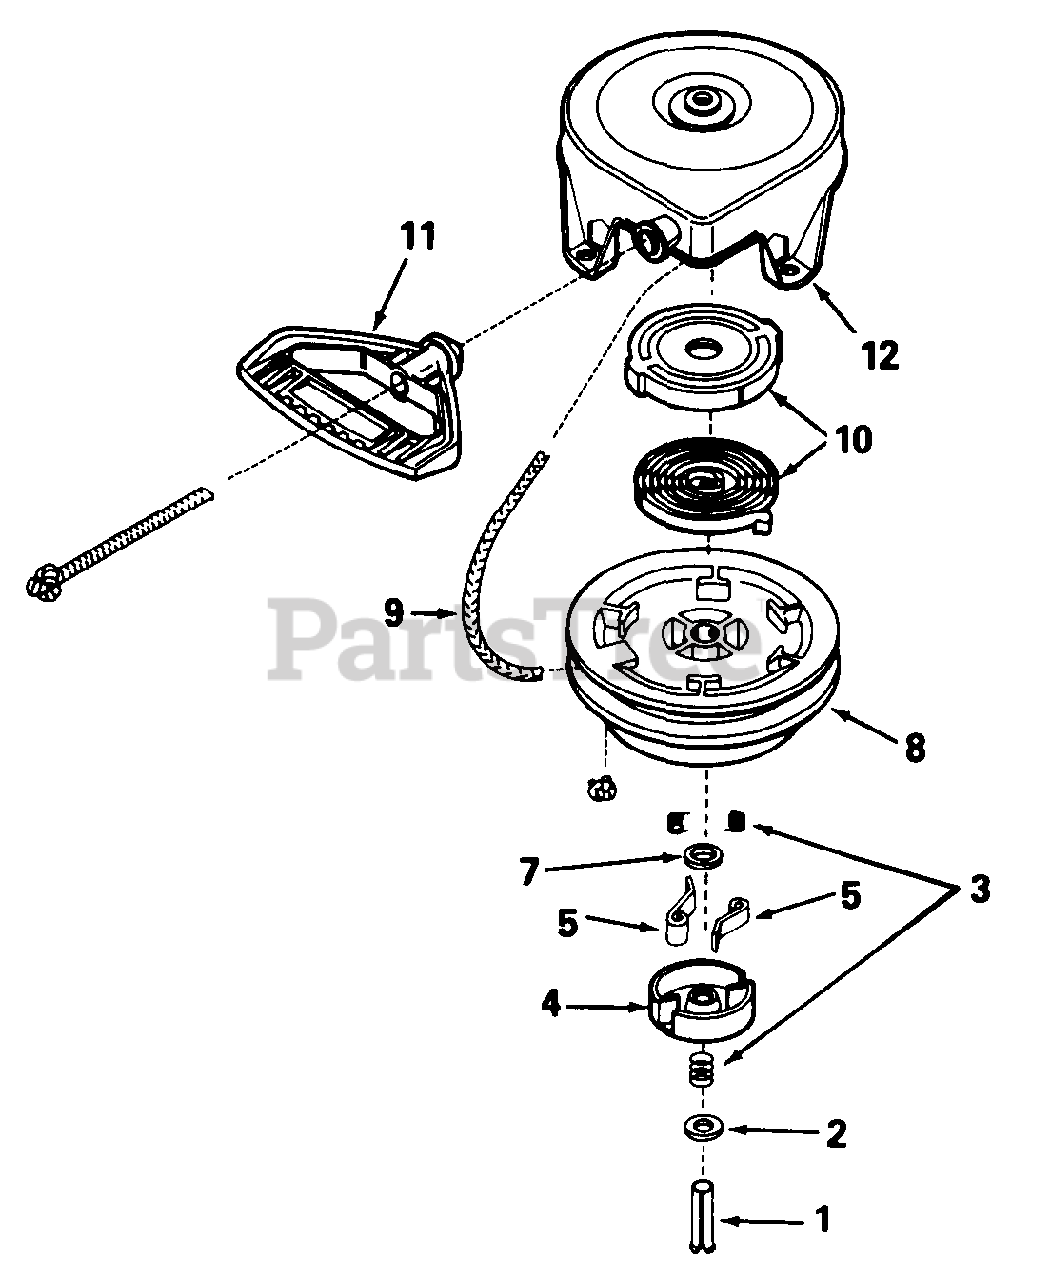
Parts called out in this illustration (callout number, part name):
1	Pin, Spring
3	Spring Ass'y., Brake & Dog
5	Dog, Starter
9	Rope, Starter
10	Spring & Keeper Ass'y.
11	Handle, Mitten Grip
12	Housing Ass'y., Starter
